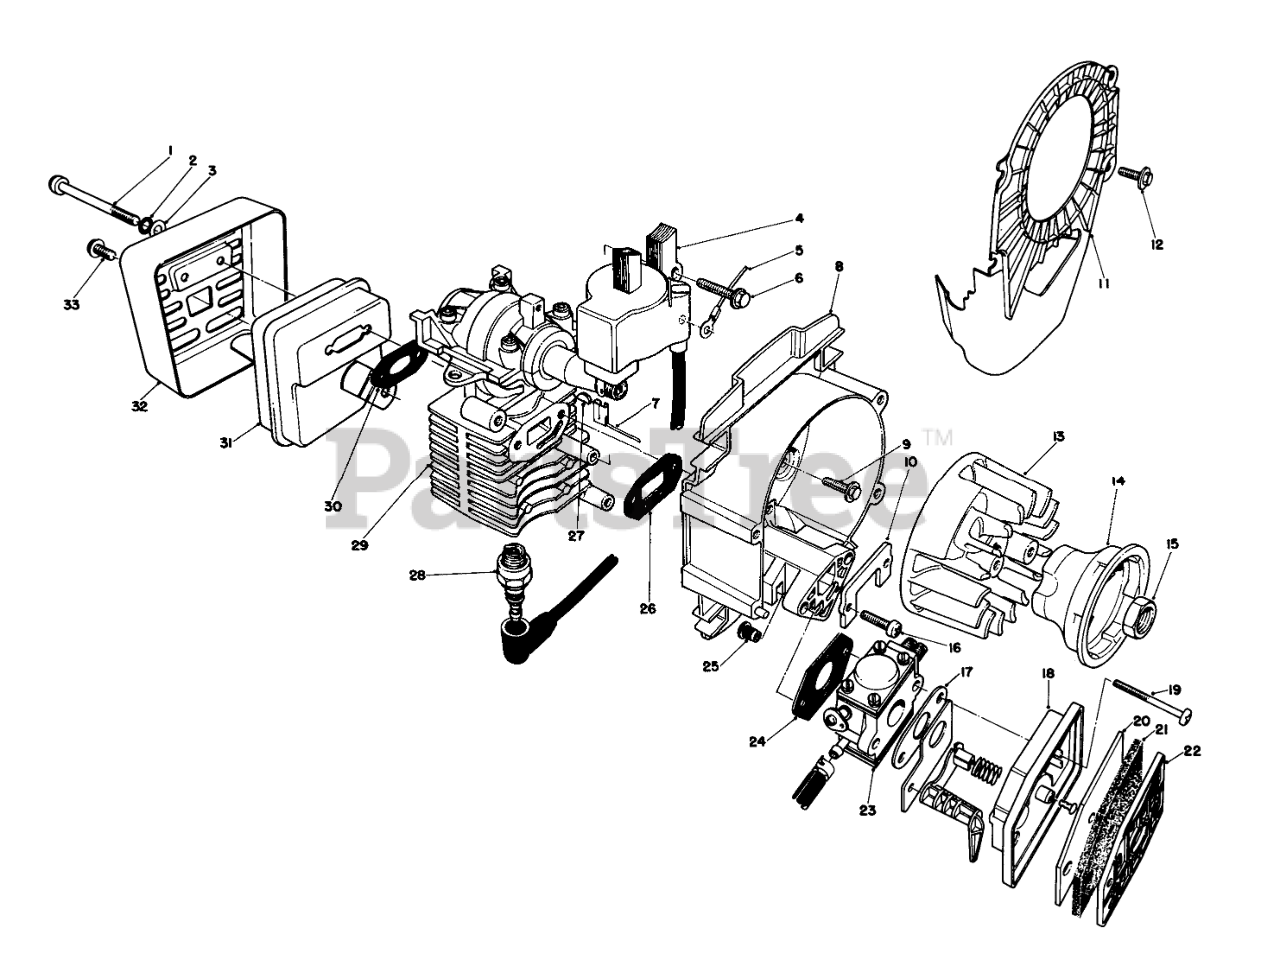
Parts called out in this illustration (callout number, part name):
1	MUFFLER SCREW
2	LOCKWASHER
3	Washer-Plain
4	CDI Module
5	Wire-Ground/Switch
6	Screw CDI
7	Wire-Coil/Switch
8	Backing Plate Assy.(Incl. Ref. #25)
9	Screw
10	Plate-Stress
11	Cooling Shroud
12	Screw-Shroud
13	Flywheel
14	Cup-Starter
15	NUT-JAM
16	Screw lntake
17	CHOKE GASKET
18	Choke & Spitback Cup Assy.
19	Screw-Carburetor
20	FILTER FELT
21	FILTER FOAM
22	FILTER COVER
23	CARBURETOR ASM
24	CARB. GASKET
25	THREADED INSERT
26	INTAKE GASKET
27	FLYWHEEL KEY
28	SPARK PLUG (NGK)
29	SHORT BLOCK ASM
30	EXHAUST GASKET
31	Muffler Assembly
32	MUFFLER SHIELD WA
33	Screw, Muffler Tab
